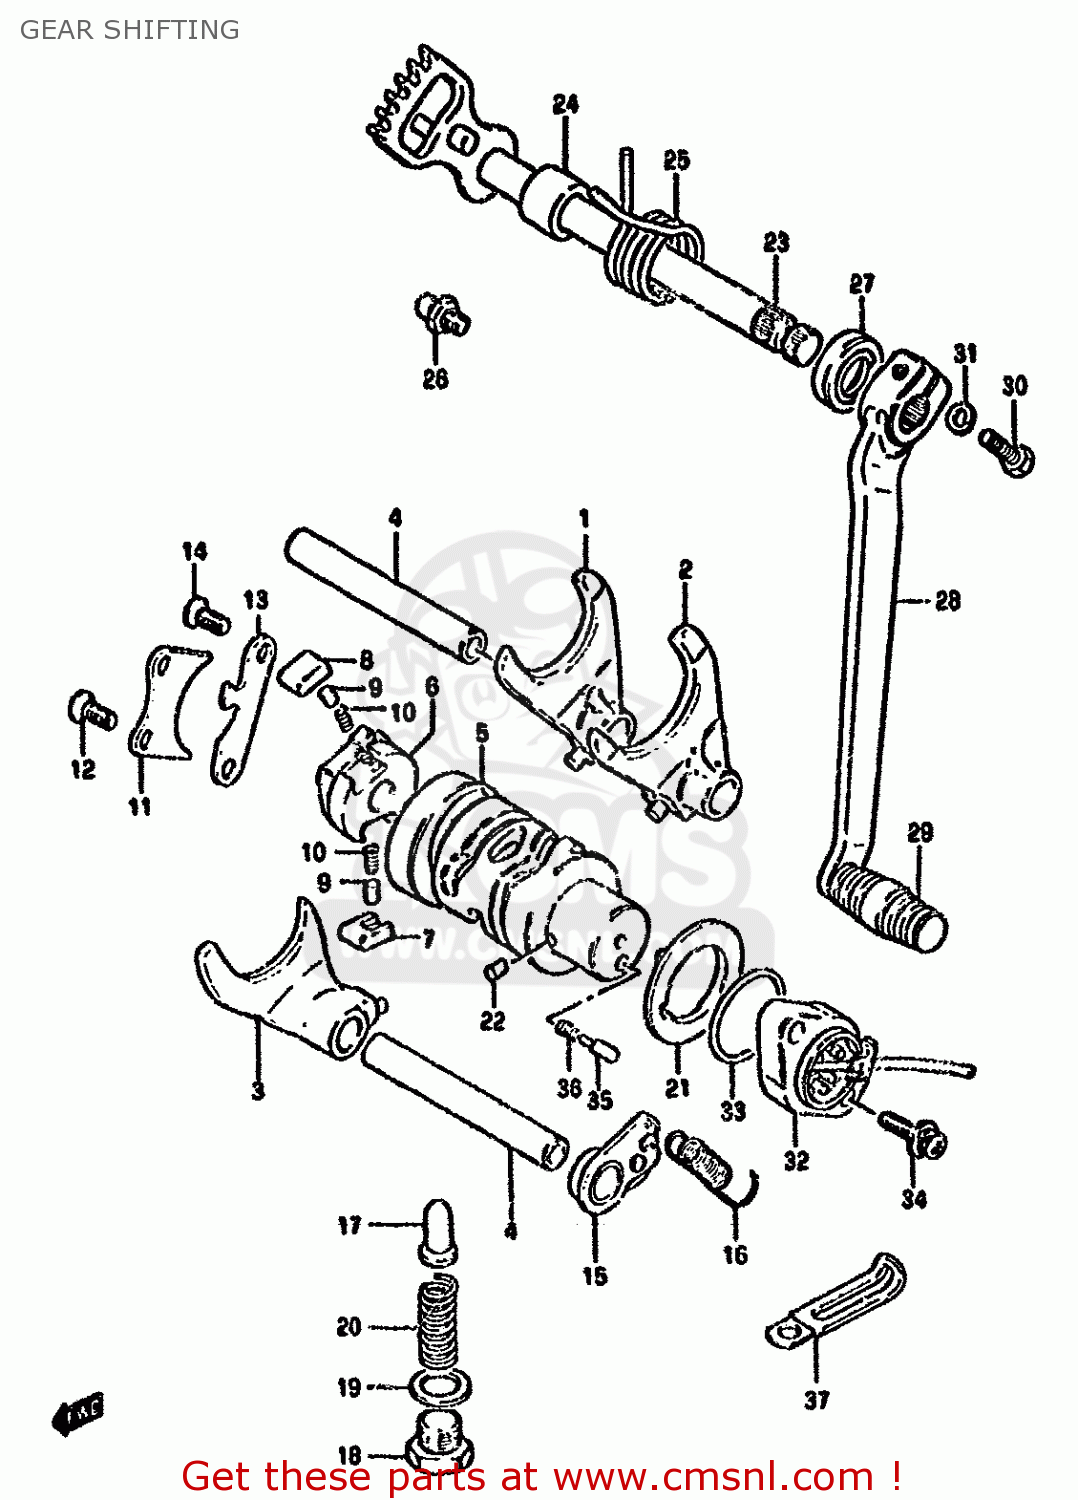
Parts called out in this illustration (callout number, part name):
1	FORK,GEAR SHIFT NO.1
2	FORK,GEAR SHIFT NO.1
3	FORK,GEAR SHIFT NO.3
4	SHAFT,GEAR SHIFT FORK
5	CAM,GEAR SHIFT
6	GEAR,GEARSHIFT CAM DRIVE
7	PAWL,GEAR SHIFT NO.1
8	PAWL,GEAR SHIFT NO.2
9	PIN(5X8)
10	SPRING
11	LIFTER,GEAR SHIFT POLE
12	SCREW
13	GUIDE,GEAR SHIFT CAM
14	SCREW
15	STOPPER,GEAR SHIFT CAM
16	SPRING
17	STOPPER,GEAR SHIFT CAM NO.2
18	PLUG (14X12)
19	GASKET(14X19.2X2) (NAS)
20	SPRING
21	PLATE,GEAR SHIFT CAM STOPPER
22	PIN 4X6
23	SHAFT,GEAR SHIFT
24	SPACER(12X20X15.3)
25	SPRING
26	STOPPER,GEAR SHIFT CAM
27	OIL SEAL
28	LEVER ASSY,GEAR SHIFT
29	RUBBER,GEAR SHIFT PEDAL
30	BOLT
31	LOCK WASHER
32	BASE ASSY,GEAR SHIFT TERMINAL
33	O-RING (D:2.4 ID:26.2)
34	SCREW
35	PIN(5X15.5)
36	SPRING
37	CLAMP
